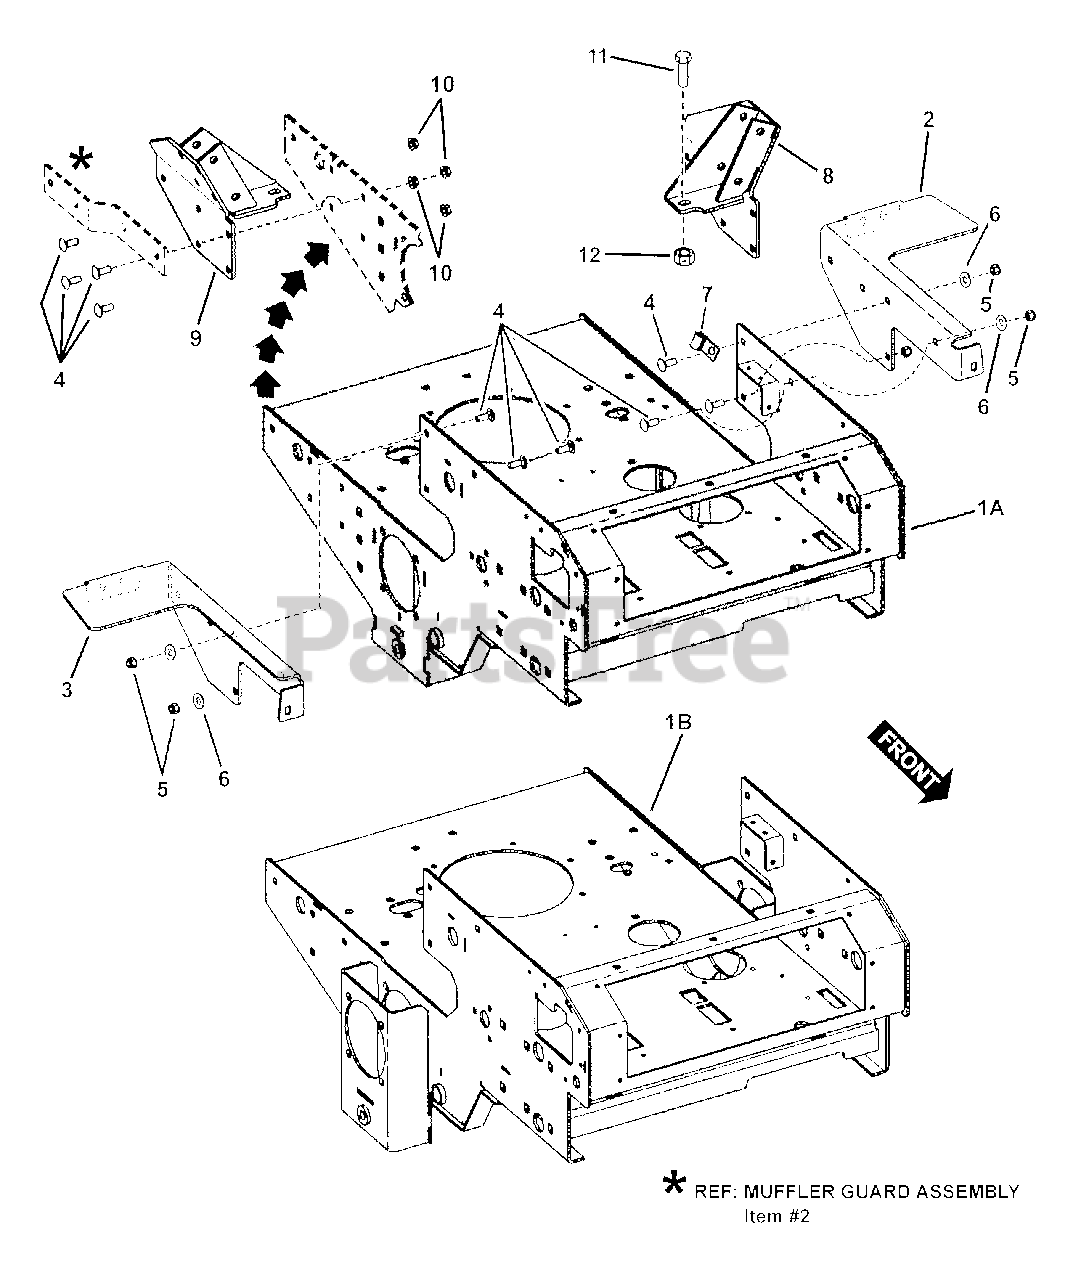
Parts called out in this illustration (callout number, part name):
1A	WELDMENT, Rear Frame (48" & 52" Deck)
1B	WELDMENT, Rear Frame (61" Deck)
2	WELDMENT, Left Hand Fuel Tank Bracket
3	WELDMENT, Right Hand Fuel Tank Bracket
4	BOLT, 3/8-16 x 1" Square Neck Carriage GR 5
5	NUT, 3/8-16 Hex Nyloc
6	WASHER, 3/8" Flat
7	CLIP, Open 3/8" Cushioned
8	WELDMENT, Right Hand Socket
9	WELDMENT, Left Hand Socket
10	NUT, 3/8-16 Hex Flange Lock
11	SCREW, 1/2-13 x 1-1/2" Hex Head Cap
12	NUT, 1/2-13 Hex Center Lock, GR 5
